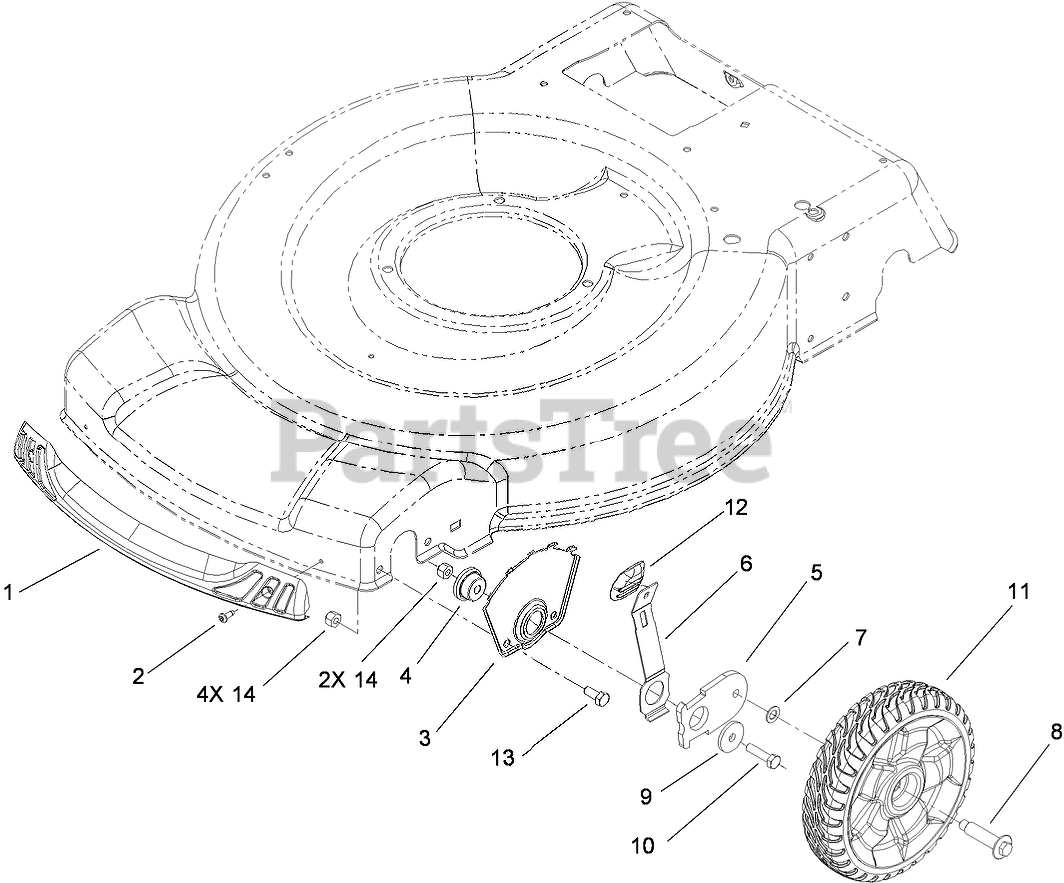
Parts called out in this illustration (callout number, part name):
1	BUMPER
2	SCREW-FORMING, THREAD
3	PLATE-HOC, FRONT
4	Bushing-Mount, HOC
5	ARM-PIVOT, FRONT
6	Arm-Spring
7	WASHER
8	BOLT-SHOULDER
9	Washer-Flat
10	SCREW-HH
11	8 INCH WHEEL ASM
12	Knob-Lever, HOC
13	SCREW-HH
14	NUT-LOCK, NI
